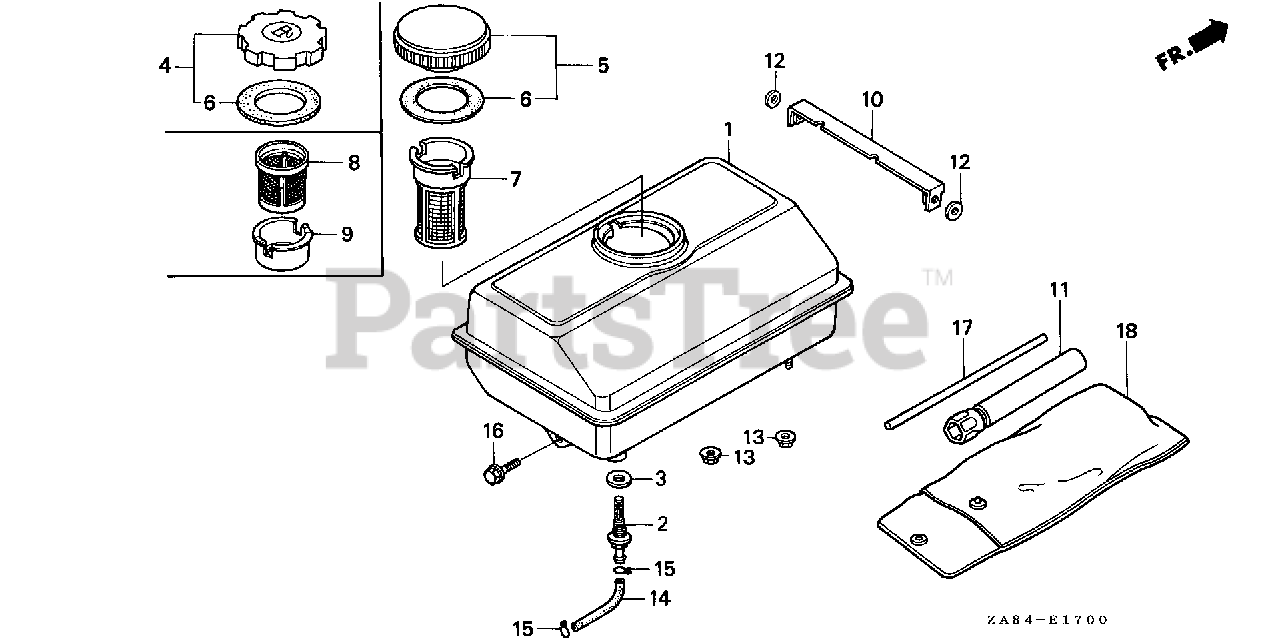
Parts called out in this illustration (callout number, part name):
1	TANK ASSY., FUEL *NH31* (MCKINLEY WHITE)
1	TANK, FUEL
1	TANK, FUEL *NH31* (MCKINLEY WHITE)
2	JOINT, FUEL TANK
3	GASKET, FUEL TANK JOINT
3	O-RING (13.5X1.5) (ARAI)
5	CAP, FUEL FILLER
6	GASKET, FUEL FILLER CAP
7	FILTER, FUEL
8	FILTER, FUEL
9	HOLDER, FUEL FILTER
10	STAY, CONTROL BOX
11	WRENCH, SPARK PLUG (NOT AVAILABLE)
12	WASHER, PLAIN (6.5X15)
13	NUT-WASHER (6MM)
14	BULK HOSE, FUEL (4.5X3000) (4.5X55)
15	CLIP, TUBE (B8)
16	BOLT, FLANGE (6X14)
17	BAR A, HANDLE
